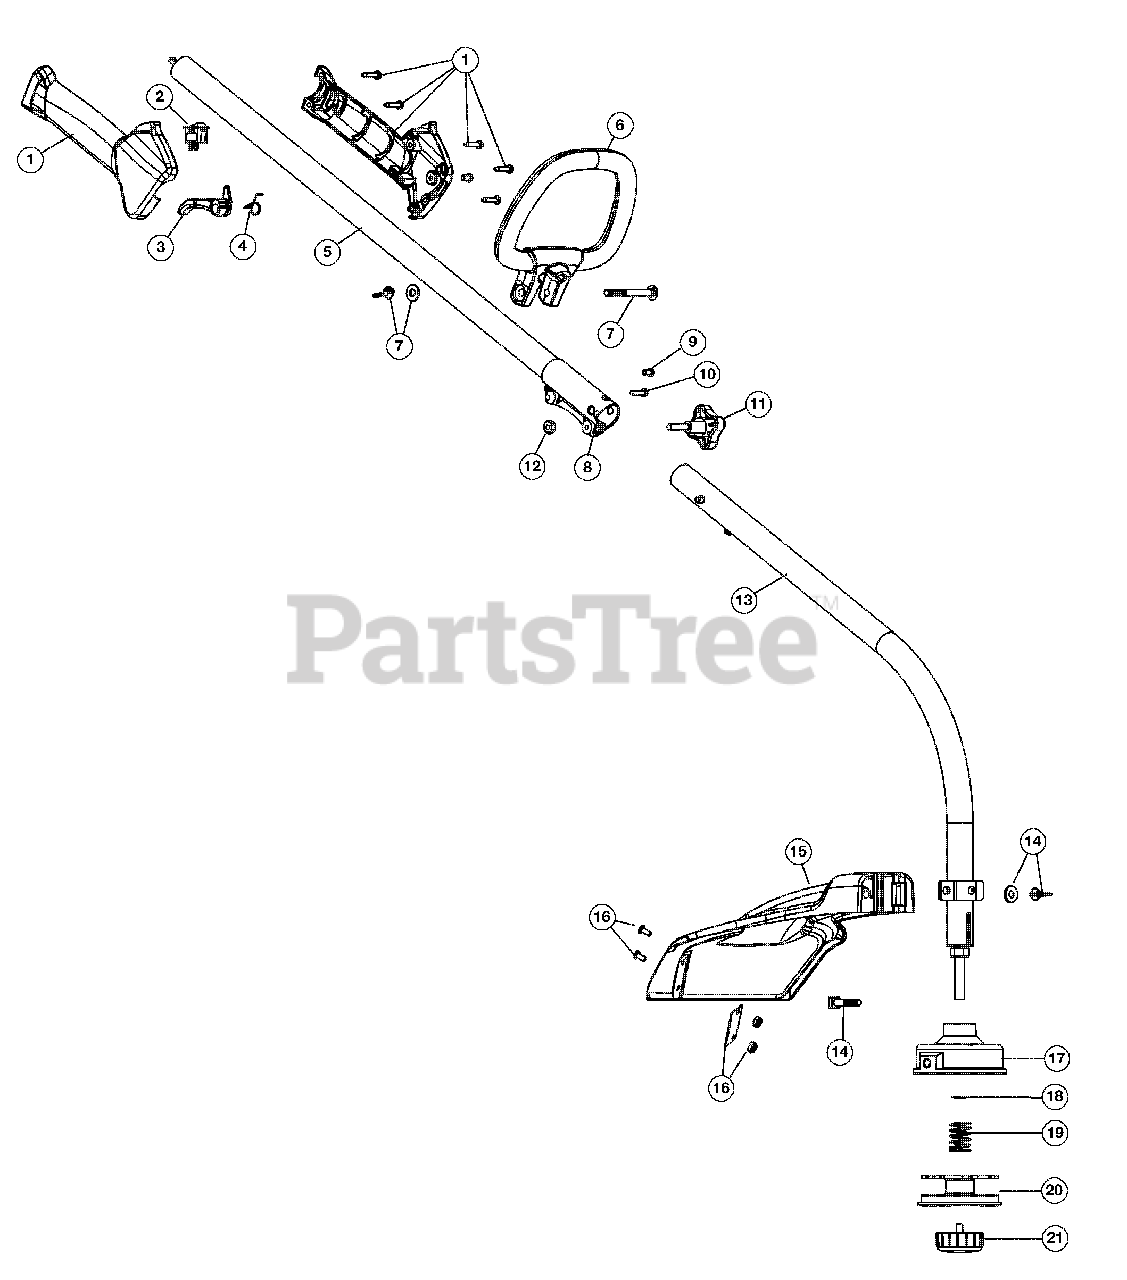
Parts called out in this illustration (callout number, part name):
1	Throttle Housing Assembly
3	Throttle Trigger
4	Throttle Trigger Spring
5	Upper Shaft Housing Assembly
6	D-Handle
7	D-Handle Hardware Assembly
8	Split Boom Coupler
9	Anti Rotation Screw
11	Adjustment Knob
12	Knob Retainer Nut
13	Lower Shaft Housing Assembly
14	Shield Mounting Hardware
15	Shield Assembly
16	Blade Assembly
17	Outer Spool Assembly
20	Inner Reel
21	Bump Head Knob Assembly
